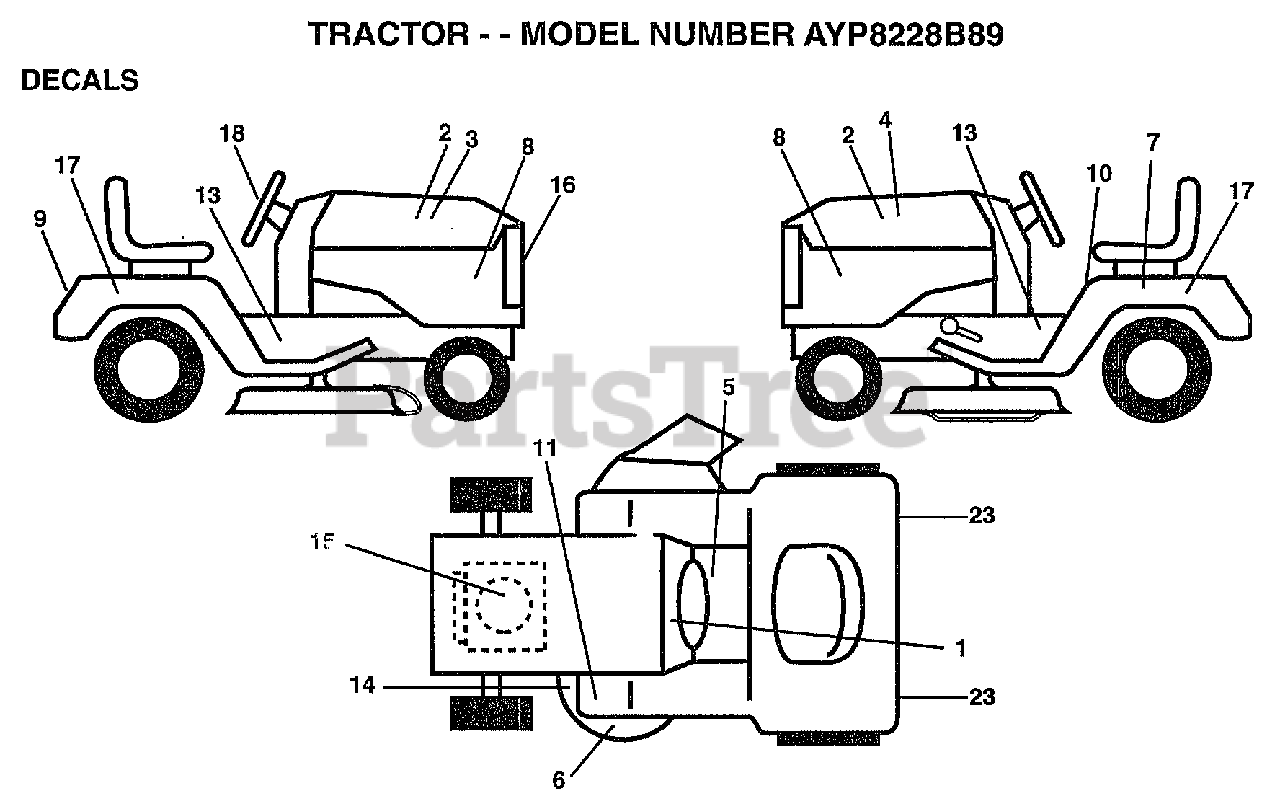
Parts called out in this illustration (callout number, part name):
1	"DECAL-INST,OPER"
2	NAMEPLATE.HD.WIZA
3	DECAL.HD.RH.WIZRD
4	DECAL.HD.LH.WIZRD
5	DECAL BRAK PARK
6	DECAL DECK WIZ +
7	DECAL.BATRY.3-3908
8	DECAL.SIDE.PANEL
10	"DECAL DANGER,FEND"
13	DECAL CHASSIS 50
15	DECAL, ENGINE
16	DECAL.GRILLE.WIZ+
17	DECAL.FENDER.WIZ
18	DECAL INS STG WHL
23	REFLECTOR-TAIL YT
